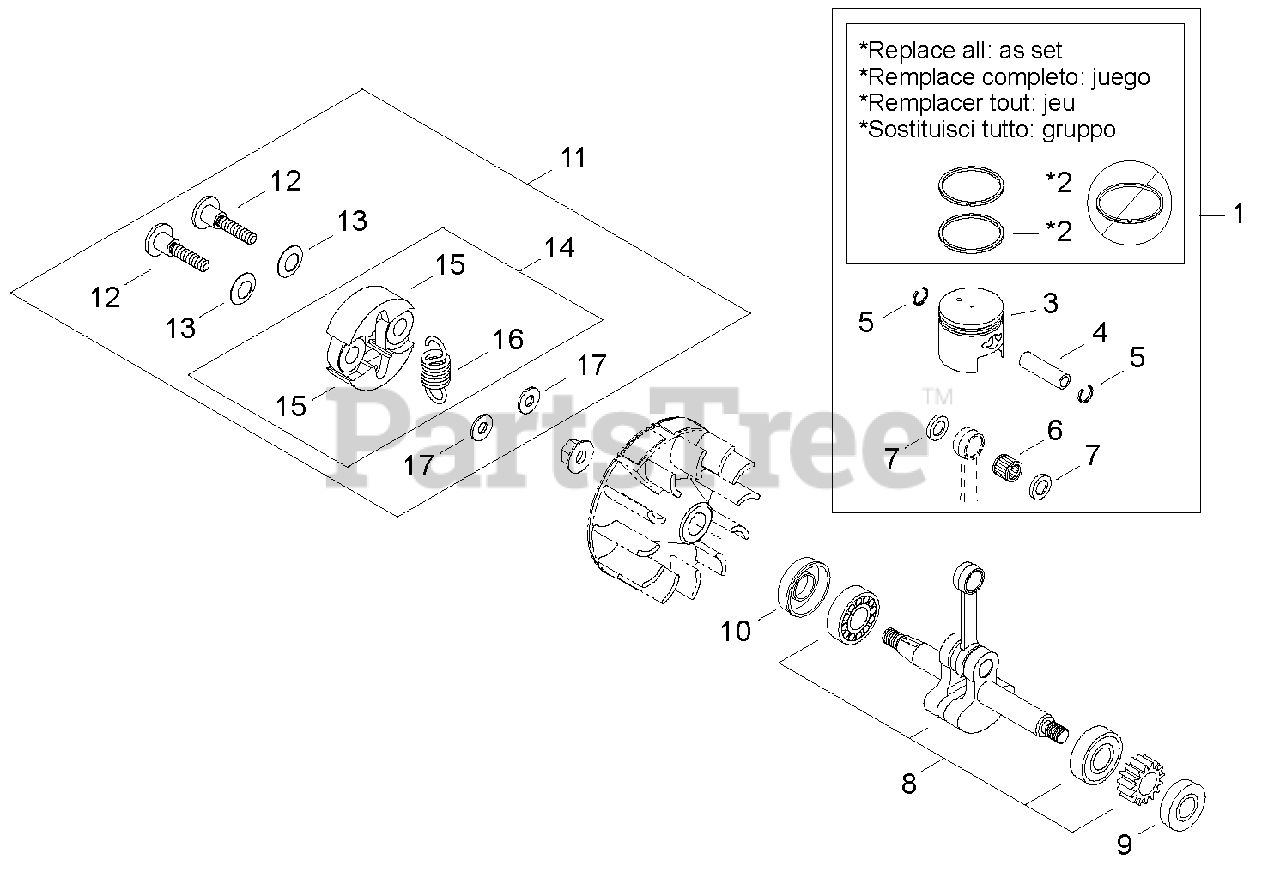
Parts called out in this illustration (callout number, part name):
1	PISTON KIT
2	RING, PISTON
3	PISTON
4	PIN, PISTON
5	RING, RETAINING
6	BEARING, NEEDLE
7	WASHER, THRUST - 10
8	CRANKSHAFT ASSY
9	SEAL, OIL - 12
10	SEAL, OIL
11	CLUTCH SHOE ASSY
12	BOLT, CLUTCH
13	WASHER - SPRING
14	CLUTCH SHOE ASSY
15	SHOE, CLUTCH
16	SPRING, CLUTCH
17	WASHER - 6
